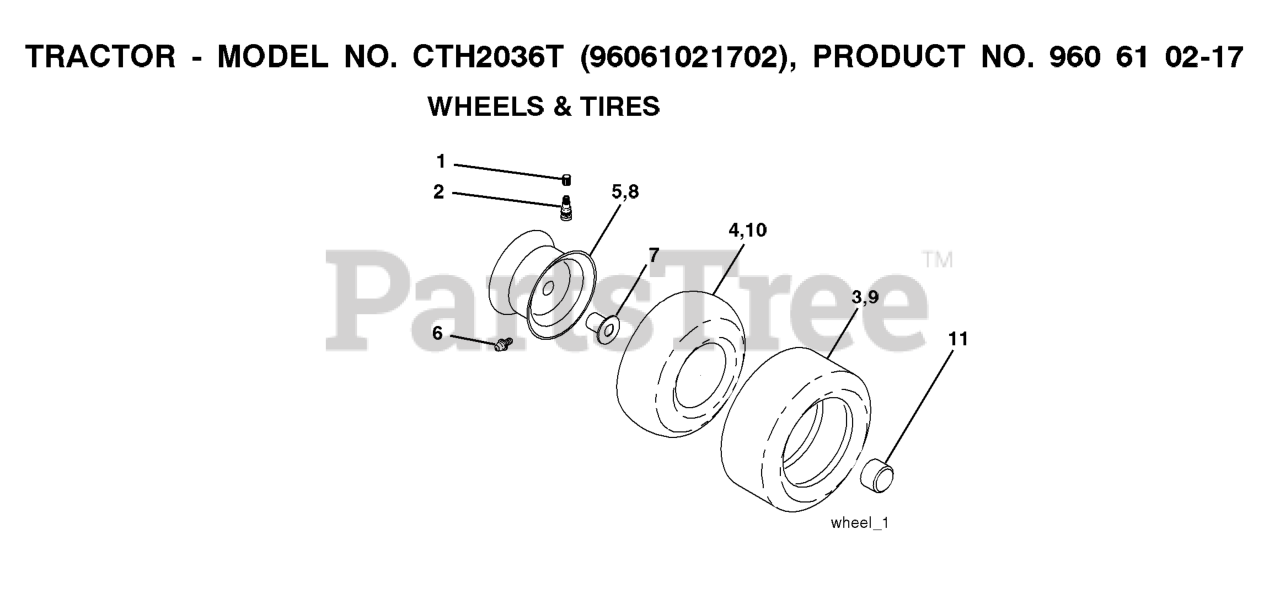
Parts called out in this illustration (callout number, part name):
2	VALVE STEM LT
3	TIRE HEAVY DUTY
4	TUBE.5.3/4.5/6
5	RIM ASM 6" FRONT SILVER
6	FITTING LT
7	BEARING T
8	RIM ASM 8" REAR SILVER
9	TIRE.TS.20X10-8
10	TUBE
11	CAP, AXLE BLK
